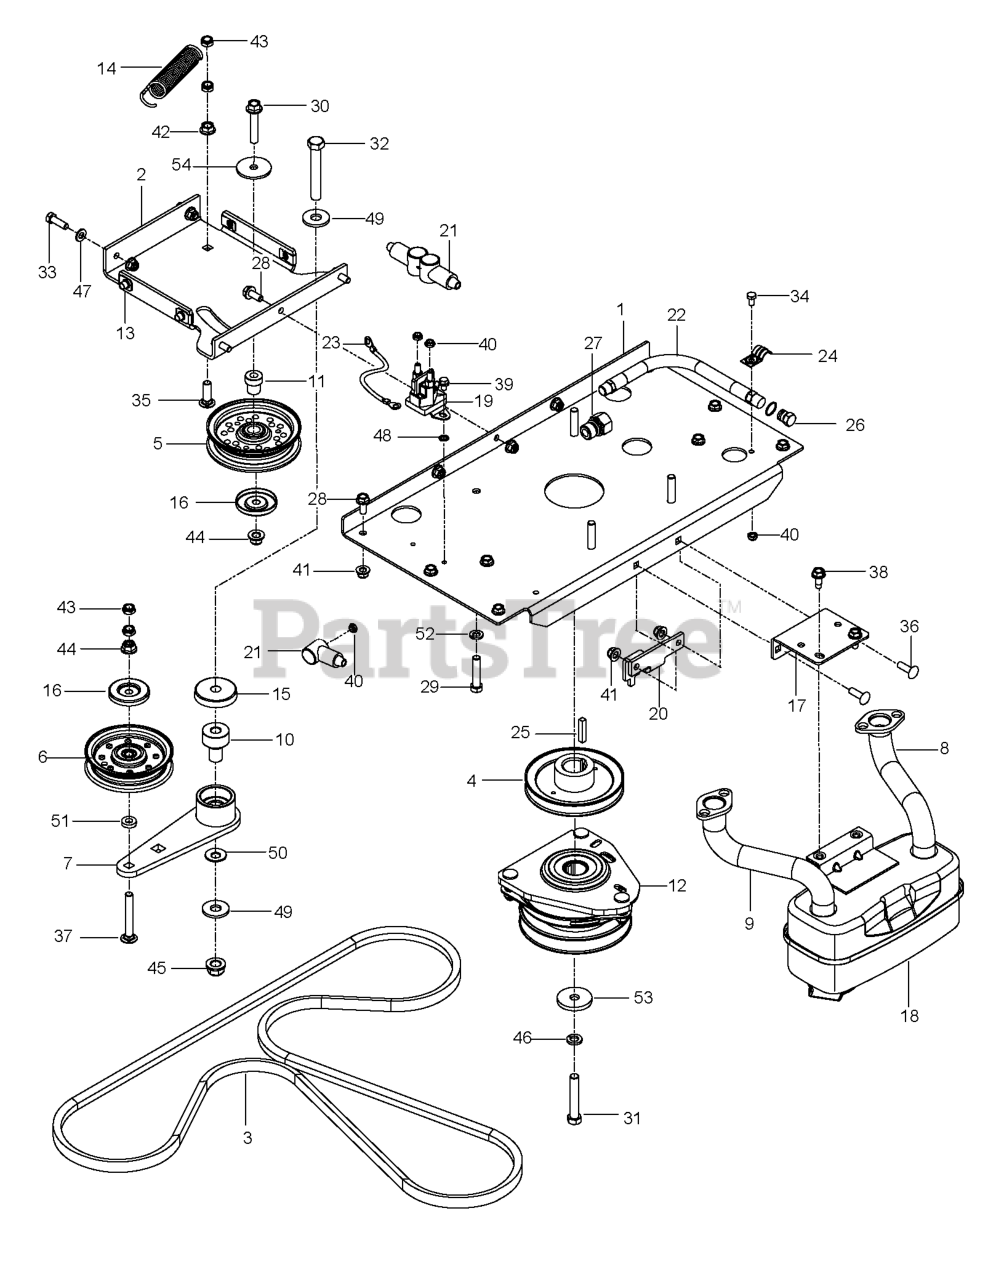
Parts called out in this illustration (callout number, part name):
1	PLATE, ENGINE, BLK
2	PLATE, IDLER, BLK
3	BELT, HYDRO, 3400
4	PULLEY.DRIVE.XMSN
5	IDLER PULLEY
6	PULLEY.IDLER.FLAT.46.PR.DR.
7	ARM, IDLER, STEEL, W/BGS
8	TUBE.EXHAUST.RH.FR961/FR730
9	TUBE.EXHAUST.LH.FR961/FR730
10	PIVOT, BEARING
11	PIVOT, IDLER
12	CLUTCH MZ ZTR GT.48/54"1.125"
13	U-CLIP 5/16-18 NUT RETAINER
14	SPRING, PUMP
15	SHIELD, DUST
16	DUST SHIELD
17	BRKT, MUFFLER, BLK
18	MUFFLER ASM TWIN
20	BRACKET.CLUTCH.STOP.PNTX431
22	HOSE.ASSEMBLY.OIL.DRAIN
23	CABLE POSITIVE
25	KEY, 1/4 SQ X 1 1/4
26	PLUG OIL DRAIN
27	ADAPTER, OIL DRAIN
28	HHFS 5/16-18 X 3/4
29	HCS 3/8-16X1.GRD.5.ZD
30	HHFS 3/8-16 X 2.0 GD 5
31	CLUTCH BOLT7/16-20X2.5 GR596HR
32	HCS 1/2C X 3 1/4
33	HCS 5/16C X 1
34	HCS 1/4-20.
35	RHSNB 3/8-16 X 1-1/4
36	RHSSNB 5/16C X 1.0
37	RHSNB 3/8-16 X 2.75
38	BOLT 5/16-18 X 3/4
39	HWST 1/4C X 3/8
40	JAM NUT 1/4C (2 2 PW01)
41	5/16-18 NYLOC FLANGE NUT
42	NUT 3/8C WHIZ
43	NUT HEX 3/8-16 NYLON, THIN
44	NUT 3/8-16 HEX FLG NYLOC ZD
45	NUT, 1/2-13 HEX FLG NYLOC ZD
46	WASHER 7/16 LOCK
47	WASHER
48	WASHER 1/4 INT TOOTH
49	WASH USS FLAT 1/2
50	CONTACT BELLSPR 1/2
51	WASHER 3/8 X 3/4 X .187 TK
52	LOCKWASHER
53	SPINDLE WASHER
54	WASHER, 3/8 SPEC
